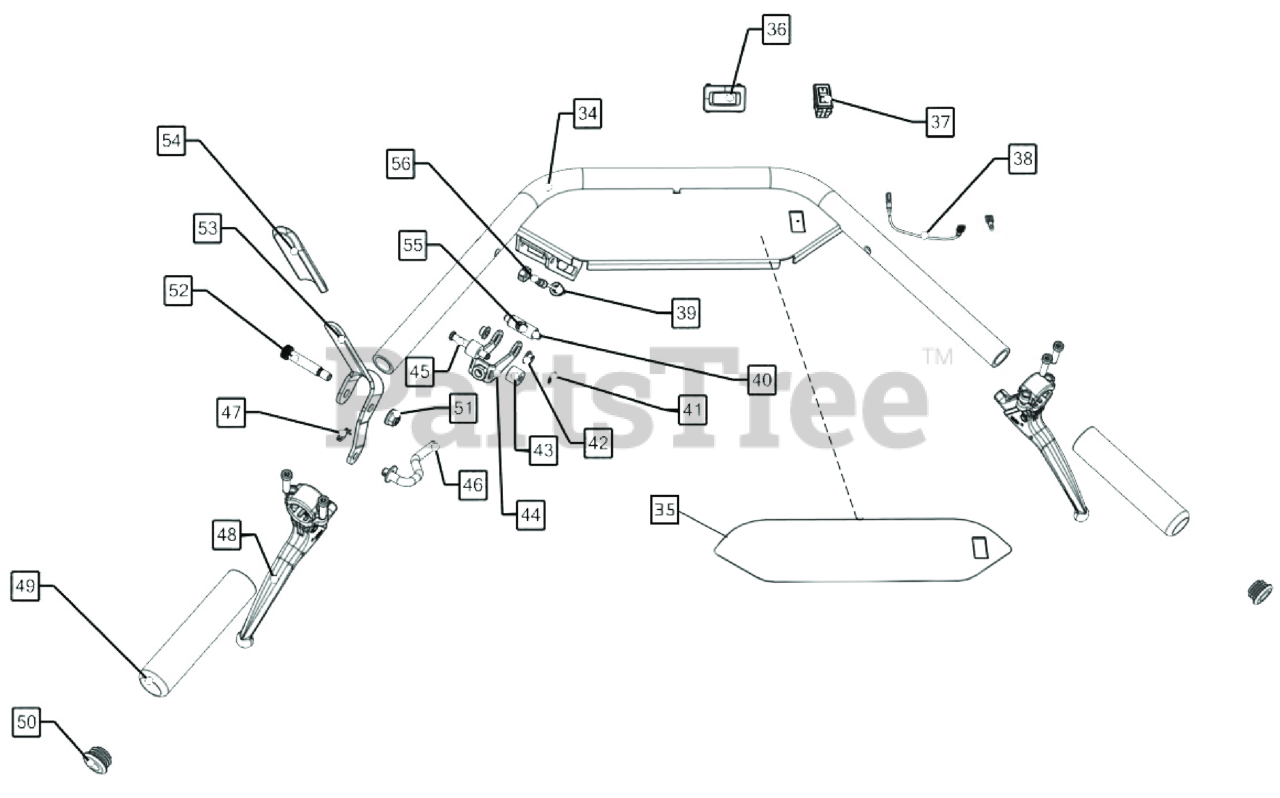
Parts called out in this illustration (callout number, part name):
34	HANDLE WA W/ LABELS
35	LABEL CONSOLE SC181H
36	HOURMETER, INDUCTIVE PANEL MOUNT
37	SWITCH LKG RKR B&S #493521
38	HARNESS, STOP SWITCH WIRE
39	BUSHING, SPLIT 0.350" NYLON BLACK
40	BARREL FITTING, CABLE SLIDE
41	RING RETAINING 5/16"
42	BUSHING, FLANGE .250" I.D. IGUS
43	SPACER, ROUND 5/8 OD X .252 ID X 1/2 LNG
44	CLEVIS, CLUTCH CONTROL SC181H
45	PIN CLEVIS 1/4" X 1 11/16" ZP
46	LINK, WIRE CLUTCH SC181H
47	PIN, RUE RING 0.313" ZP
48	CONTROL MAGURA
49	GRIP HANDLE
50	PLUG TUBE INSERT 1" OD
51	NUT-HEX-NYLK, FLG .3125-18 ZP
52	BOLT SHOULDER 3/8 X 1 1/2"
53	LEVER, CONTROL BLADE SC181H
54	GRIP LEVER 0.125" X 1" X 5" ORANGE
55	RING, RETAINING 7/32 E-CLIP SE-21
56	CABLE, CLUTCH BELT SC181H
